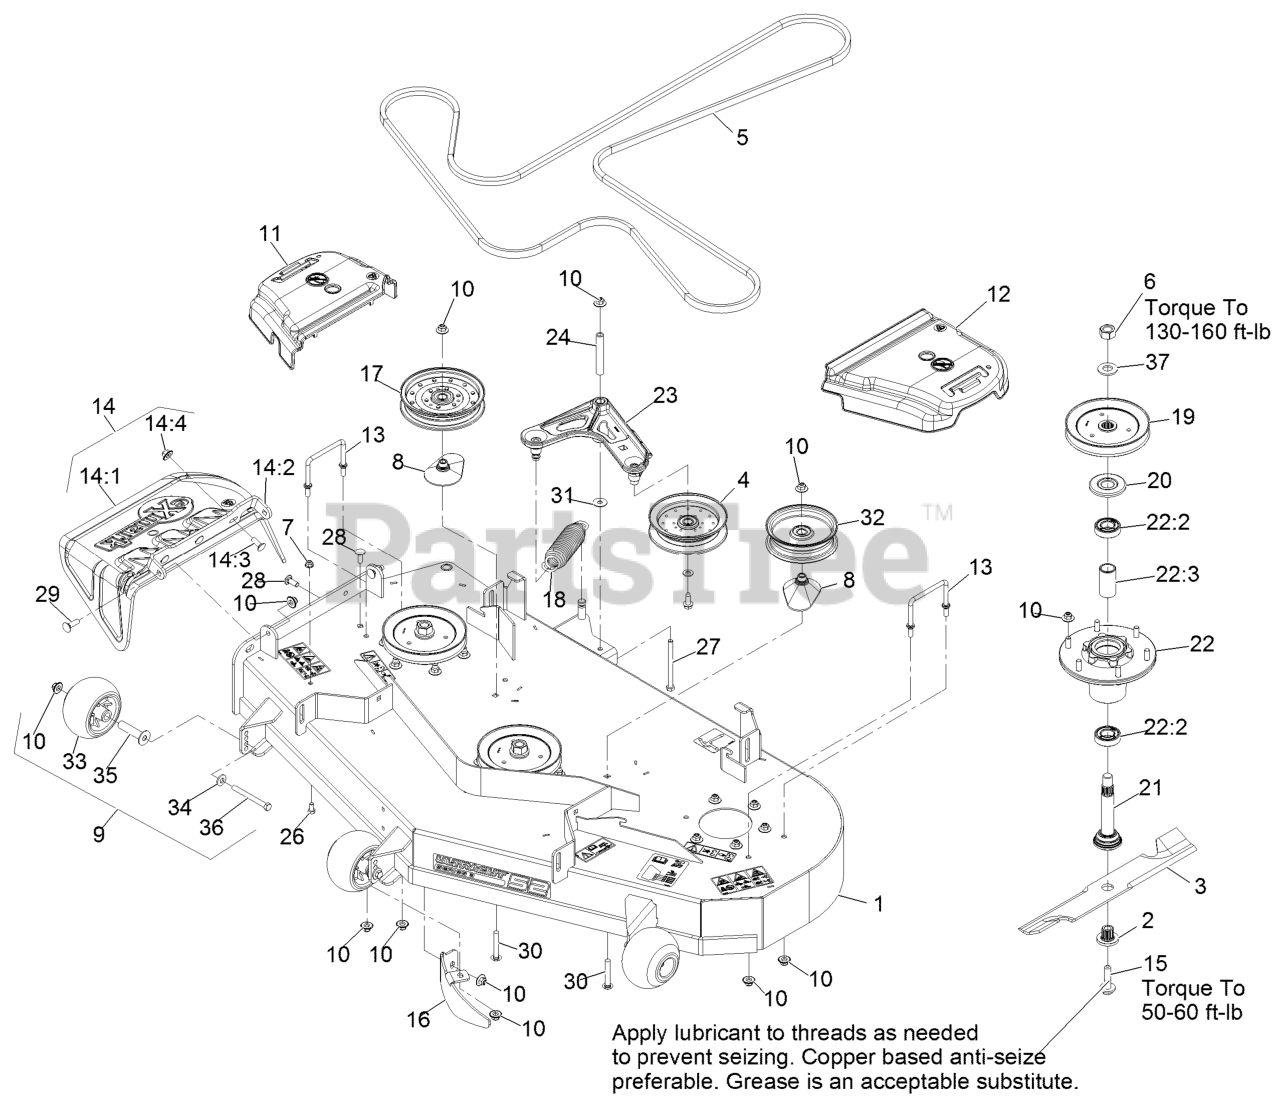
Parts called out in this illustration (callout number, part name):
1	ASM-DECK W/DECALS, 52
2	BUSHING,SPLINED
5	BELT-B162.50
6	NUT-HEX
7	NUT-HF, NI
8	SPACER-PULLEY
9	KIT, ANTI-SCALP ROLLER
10	Nut-Nyloc 3/8-16 Flg
11	COVER-BELT, RH
12	COVER-BELT, LH
13	WIREFORM-COVER
14	ASM,DISCHARGE CHUTE
14:1	CHUTE,DISCHARGE
14:2	BRACKET,DISCHARGE CHUTE
14:3	SCREW-CARR
14:4	Nut-Nyloc 3/8-16 Flg
15	SCREW,SEMS 1/2-20 X 2.19
16	BAFFLE-DOGLEG, LZE-PNS-52
18	SPRING-EXTENSION
19	SHEAVE,BLADE DRIVE 6.50
20	GUARD,BEARING TOP .989
21	ASM-SPINDLE AND SEAL
22	ASM-CUTTER HSG WITH BEARINGS
22:2	BEARING-BALL
22:3	SPACER-BEARING
23	IDLER ARM ASM
24	BUSHING
26	SCREW-HH
27	SCREW-HH
28	SCREW-CARR
29	BOLT-CARR
30	SCREW-CARR
32	IDLER-PULLEY, FLAT
33	ROLLER-SCALP, ANTI
34	WASHER-BELLEVILLE
35	AXLE, ROLLER
36	SCREW-HH 3/8-16 X 3 3/4 GR 8
